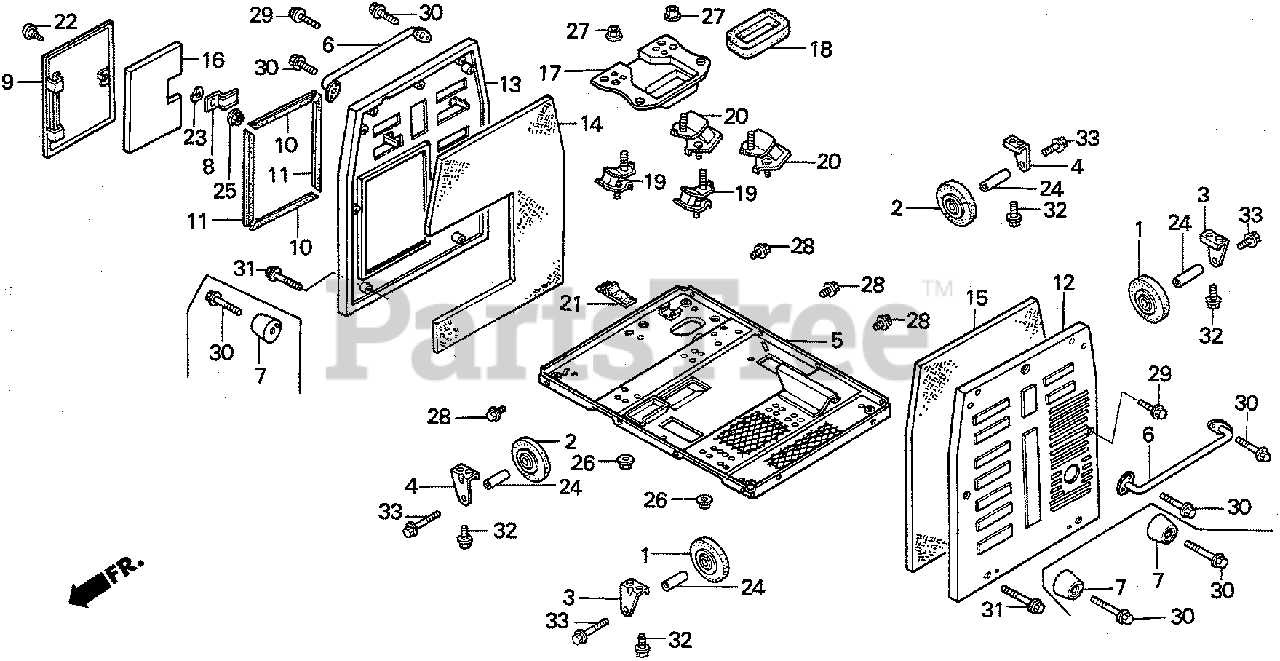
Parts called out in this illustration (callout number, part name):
1	WHEEL (100X33)
2	WHEEL (100X33)
3	BRACKET, R. WHEEL
4	BRACKET, L. WHEEL
5	FRAME (LOWER) *NH1* (BLACK)
7	RUBBER (LOWER)
8	PLATE, MAINTNENANCE LID LOCK
9	LID, MAINTENANCE *NH1* (BLACK)
10	SEAL C, MAINTENANCE LID
11	SEAL D, MAINTENANCE LID
12	PANEL, R. SIDE *NH105* (MAT BLACK)
13	PANEL, L. SIDE *NH105* (MAT BLACK)
14	INSULATOR, R. SIDE PANEL
15	INSULATOR, L. SIDE PANEL
16	INSULATOR, RR. MAINTENANCE LID
17	GUIDE, AIR (LOWER)
18	SEAL, AIR GUIDE (LOWER)
19	RUBBER (LOWER)
20	RUBBER (LOWER)
21	BAND, TOOL SETTING
22	BOLT, MAINTENANCE LID LOCK
23	WASHER, WAVE (12MM)
24	COLLAR, WHEEL SHAFT
25	NUT, FLANGE (6MM)
26	NUT, FLANGE (8MM)
27	NUT, FLANGE (10MM)
28	BOLT, FLANGE (6X12)
29	BOLT, FLANGE (6X32)
30	BOLT, FLANGE (6X35)
31	BOLT, FLANGE (6X35)
32	BOLT, FLANGE (8X16)
33	BOLT, FLANGE (8X55)
